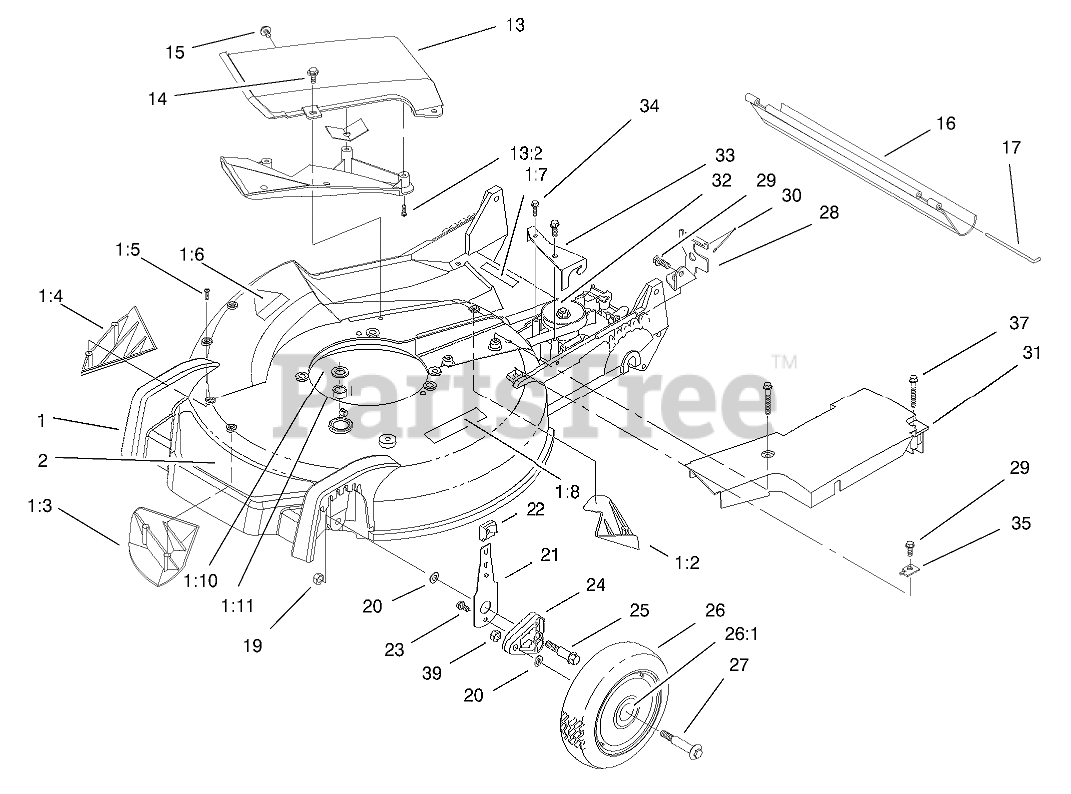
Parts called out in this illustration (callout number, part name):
1	HOUSING
1:2	KICKER-REAR
1:3	KICKER-FRONT
1:4	KICKER-RH
1:5	SCREW-PPH
1:6	DECAL-DANGER
1:7	DECAL-WARNING
1:8	DECAL-WARNING
1:10	WASHER
1:11	BEARING
2	DECAL - DECK
13	Recycler Cover ASM
13:2	SCREW-PPH
14	SCREW-HWH
15	SCREW AND WASHER ASM
16	SHIELD-TRAILING
17	ROD-SHIELD
19	NUT-LOCK
20	WASHER
21	FRONT SPRING ARM ASM
22	KNOB-ARM
23	SCREW-HWH
24	ARM-PIVOT, FRONT
25	BOLT-SHOULDER
26	WHEEL ASM
26:1	BUSHING
27	BOLT-SHOULDER
28	BRACKET-TRACTION, ADJ.
29	SCREW-HWHTF
30	RETAINER-CABLE
31	COVER-BELT
32	GEARCASE ASM
33	BRACKET-GUIDE, BELT
34	SCREW-HWHTF
35	CLAMP-CABLE
37	SCREW-HHFTF
